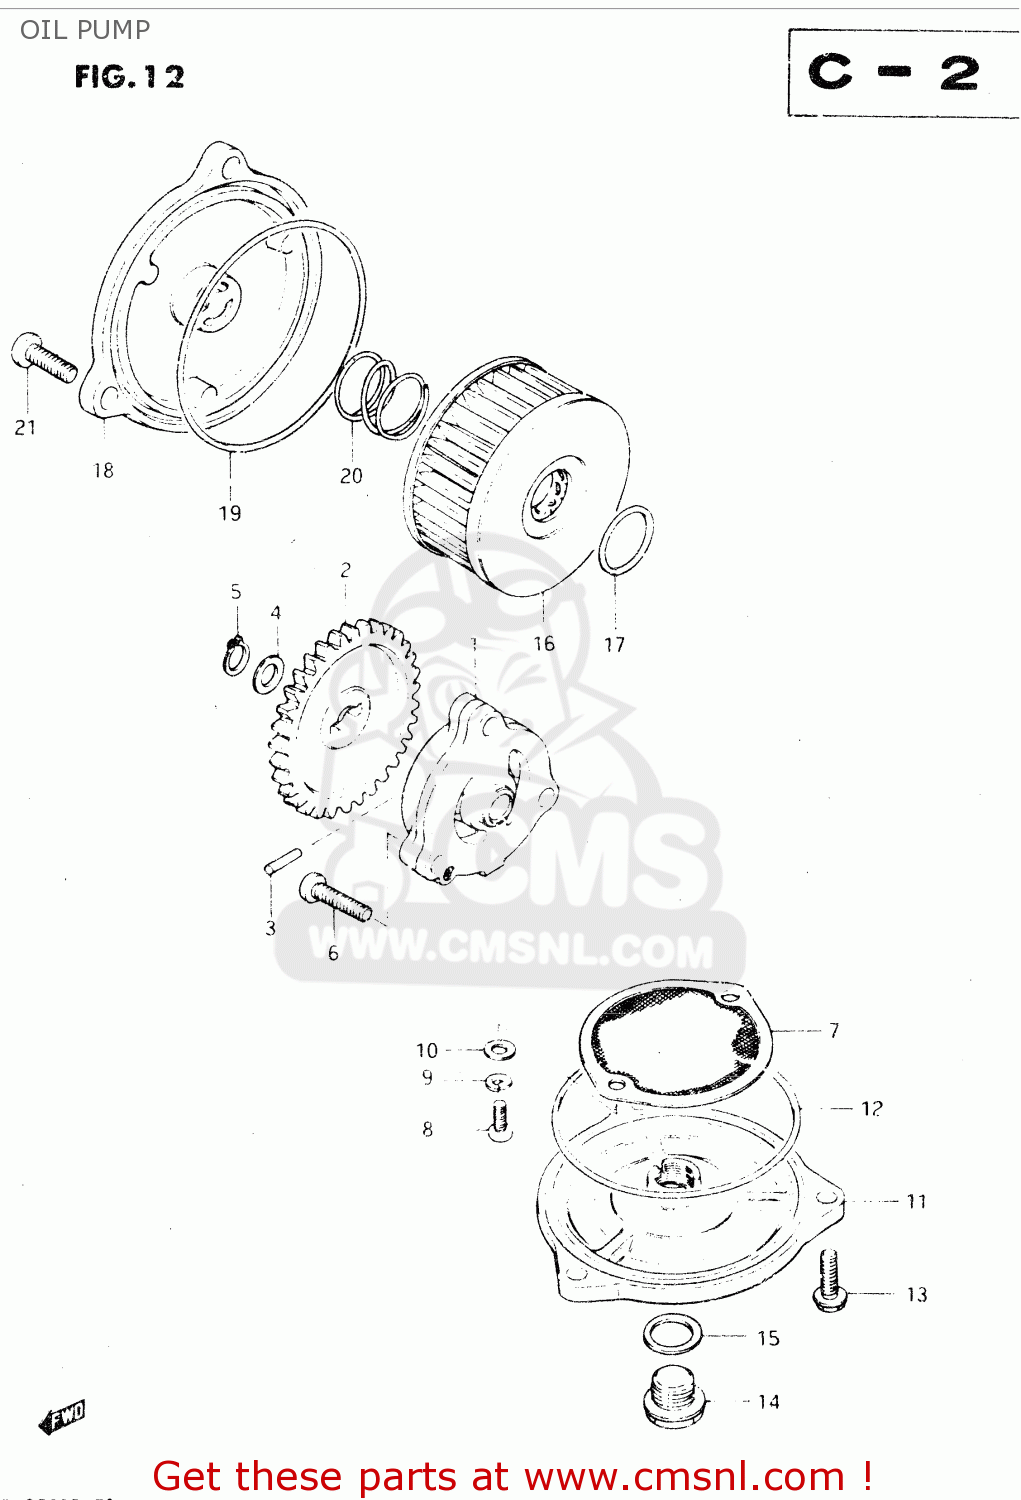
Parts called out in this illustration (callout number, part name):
1	PUMP ASSY,ENGINE OIL
2	GEAR,OIL PUMP DRIVEN(NT:33)
3	PIN(4X15.8)
4	SHIM
5	CIRCLIP
6	SCREW
7	STRAINER,ENGINE OIL
8	SCREW
9	LOCK WASHER
10	WASHER
11	CAP,OIL STRAINER
12	O RING(D:2.4,ID:85)
13	BOLT (6X20)
14	PLUG
15	GASKET(14X19.2X2) (NAS)
16	FILTER ASSY,ENGINE OIL
17	O RING(D:2.4,ID:15.8)
18	CAP,OIL FILTER
19	O RING(D:2.4,ID:73)
20	SPRING
21	SCREW
